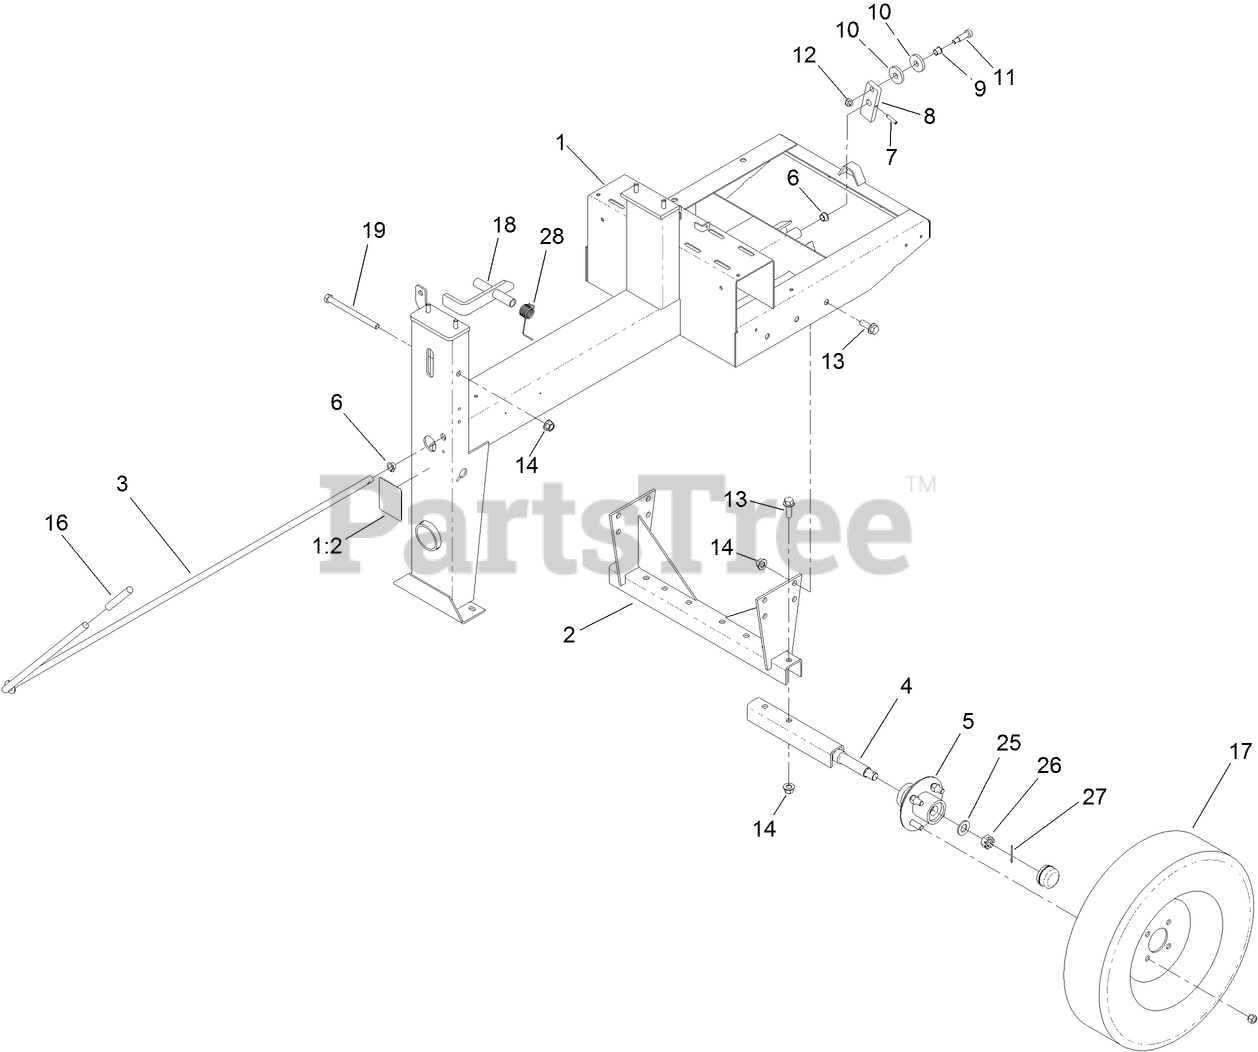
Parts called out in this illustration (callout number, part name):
1	FRAME ASM
1:2	DECAL-SAFETY CHAIN, TOWING
2	SUPPORT-AXLE
3	LEVER-CLUTCH
4	AXLE-HALF
5	HUB ASM
6	BUSHING-FLANGE
7	PIN-SPRING
8	LINK-CLUTCH
9	BUSHING-FLANGE
10	WASHER-FLAT
11	SCREW-HSBH
12	NUT-HF, NI
13	SCREW-HHF
14	NUT-LOCK
16	GRIP-HANDLE
17	TIRE AND RIM ASM
18	LATCH-DRUM
19	SCREW-HH
25	WASHER-FLAT
27	PIN-COTTER
28	SPRING-TORSION
